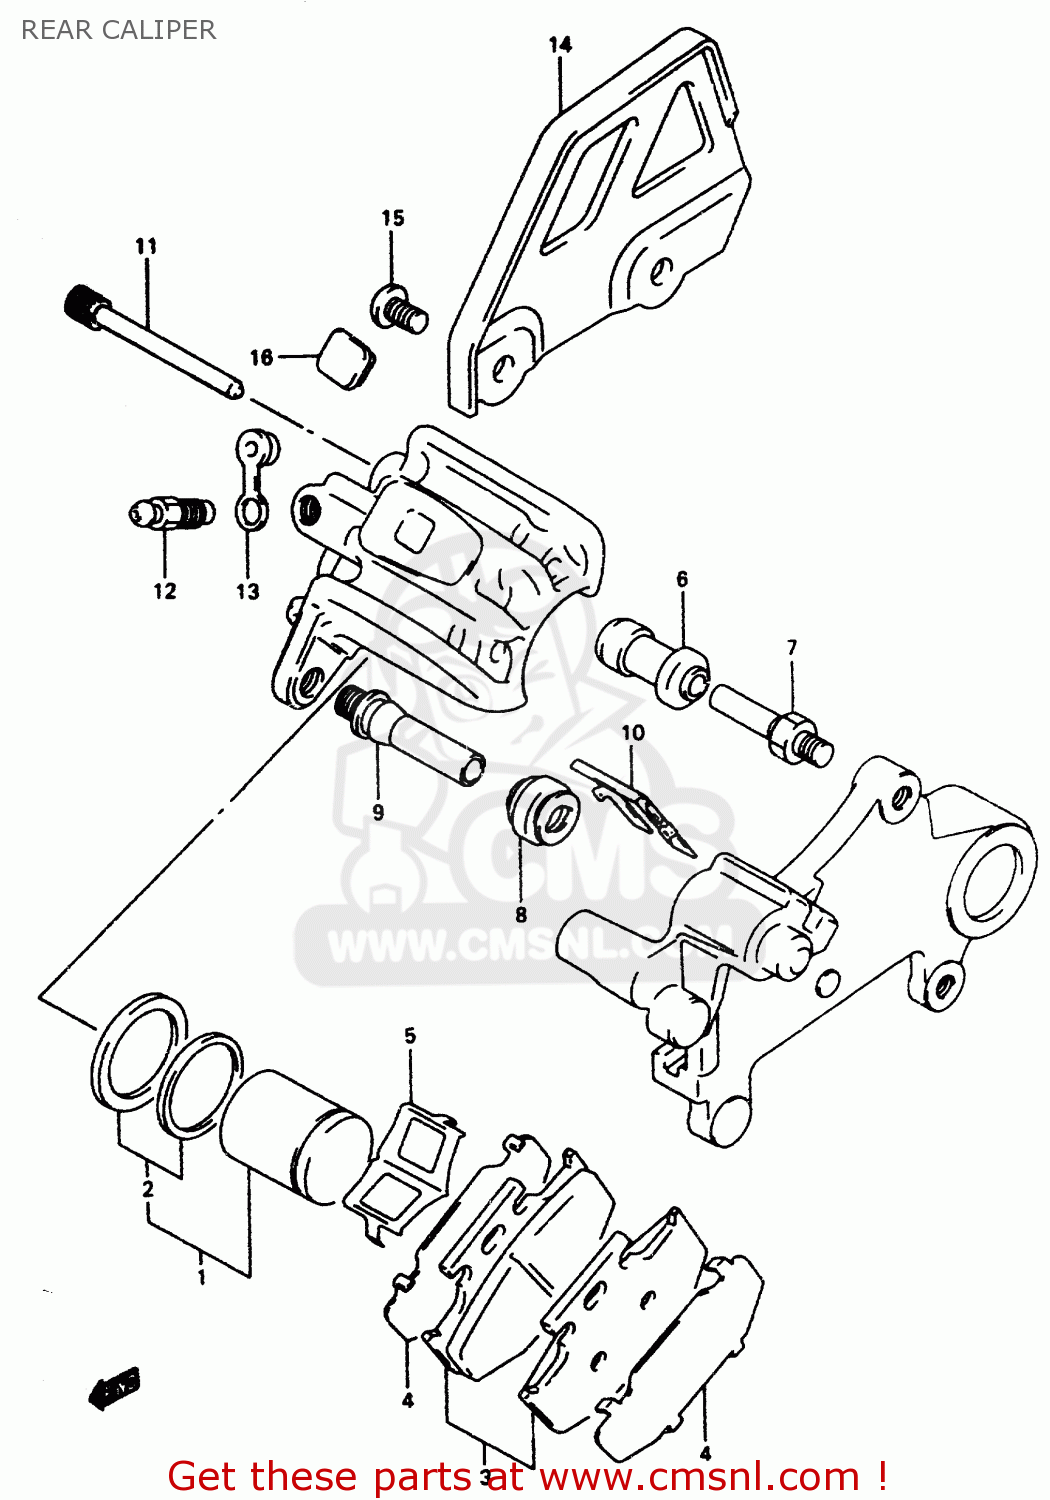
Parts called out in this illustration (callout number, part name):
1	PISTON SET
2	SEAL SET,PISTON
3	PAD SET (NAS)
4	SHIM
5	SPRING,PAD
6	BOOT
7	PIN,BOLT
8	BOOT
9	PIN
10	RETAINER,BRACKET
11	PIN,HANGER
12	BLEEDER
13	CAP,BLEEDER
14	GUARD,RR CALIPER
15	SCREW 6X12
16	COVER,RR CALIPER BODY
